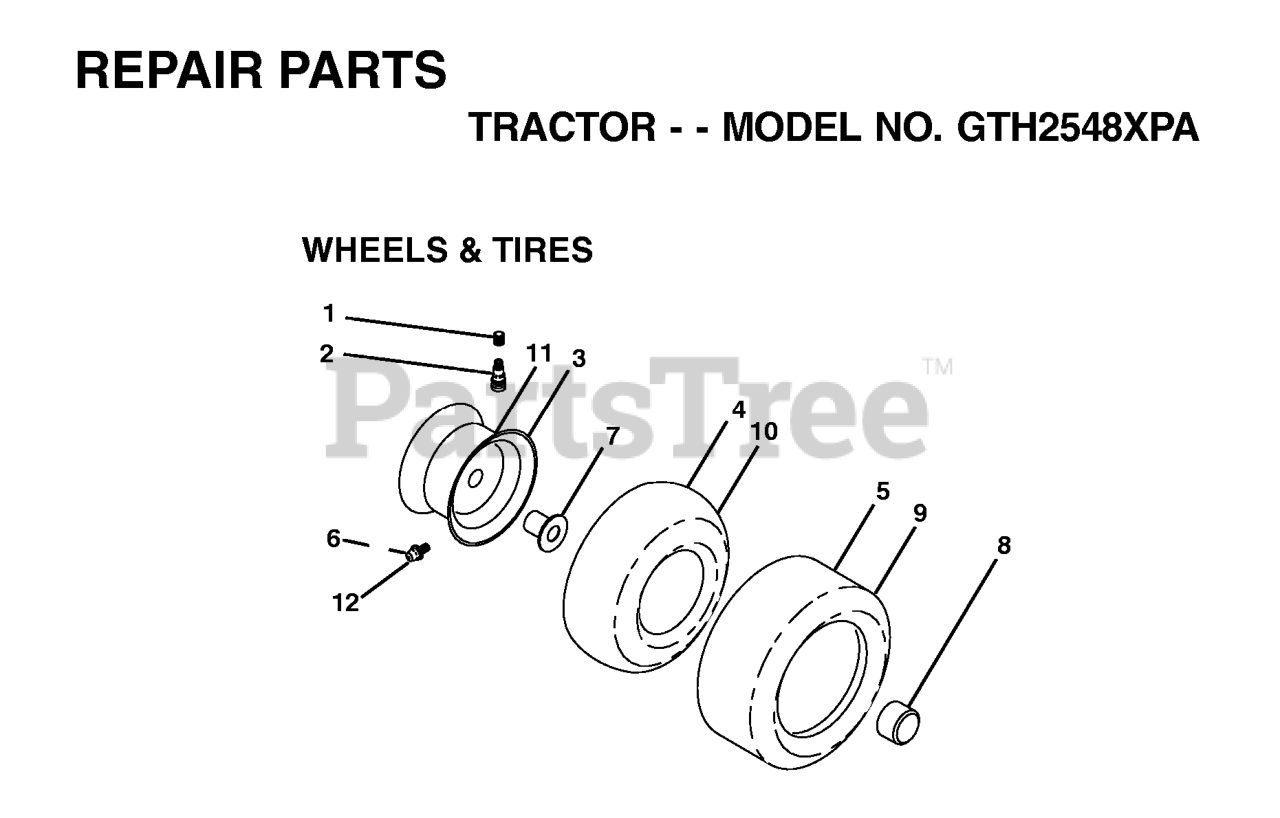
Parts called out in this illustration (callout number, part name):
2	VALVE STEM LT
4	TUBE.16X6.5/7.5-8
6	FITTING LT
7	BEARING T
8	CAP, AXLE BLK
10	TUBE.23X9.5-12
12	ZERK FITTING M
